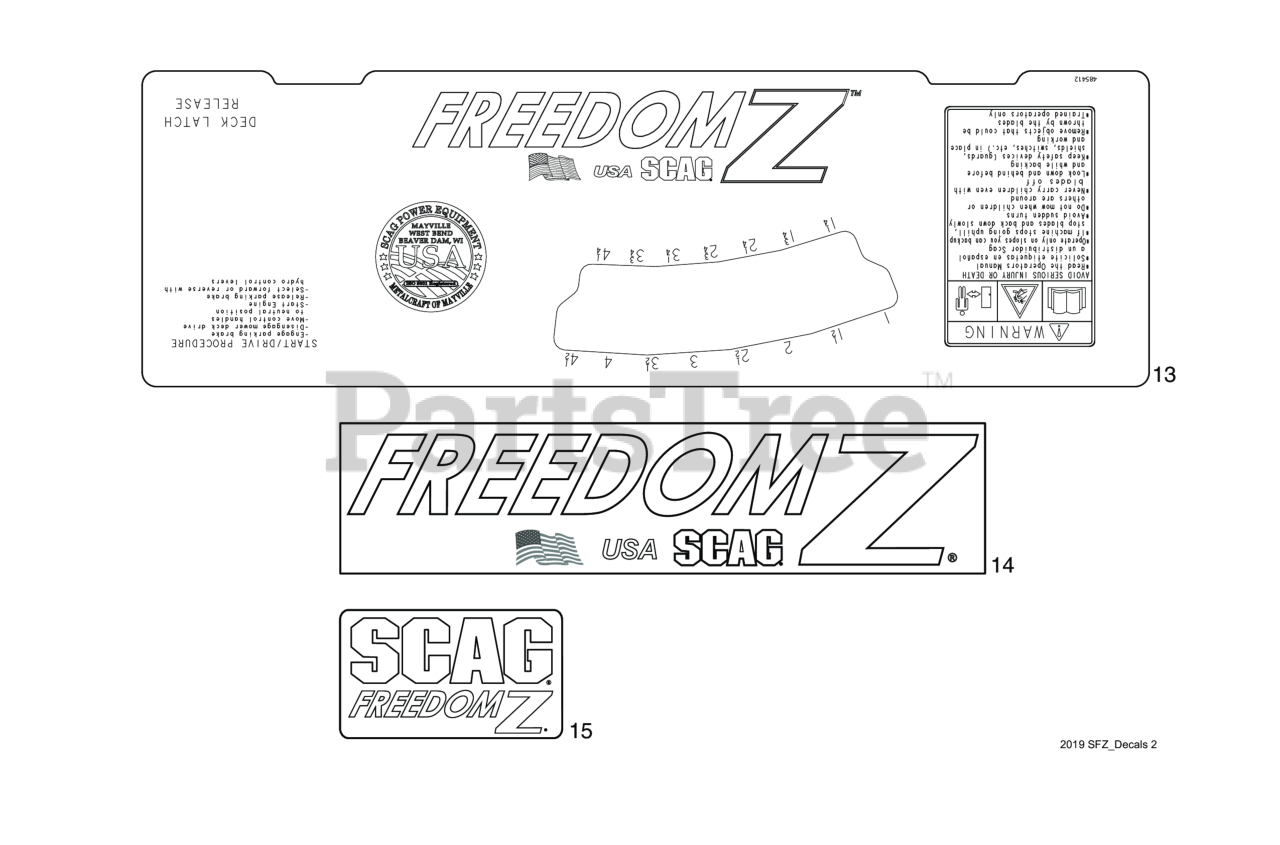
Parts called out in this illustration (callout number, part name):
13	Decal, Cutting Height
14	Decal, Freedom Z (Fuel Tank)
15	Decal, Scag Freedom Z (Fuel Tank)
